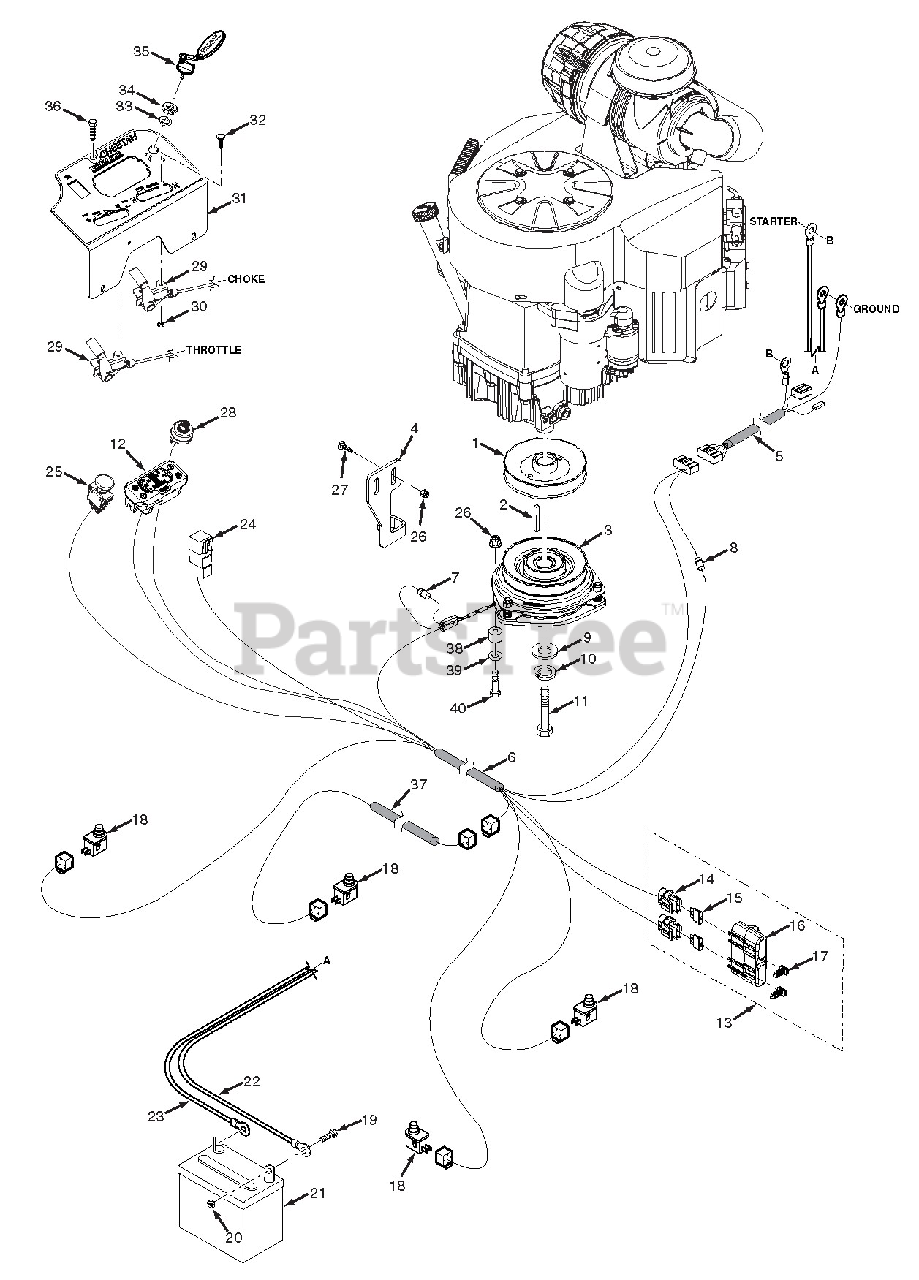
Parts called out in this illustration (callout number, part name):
1	Pulley, 5.80 Dia. - 1.125 Bore
2	Key, 1/4 x 1/4 x 3-1/4"
3	Electric Clutch w/Tag - GT-3.5 (FX850)
3	Electric Clutch w/Tag - GT-5 (FX921)
4	Bracket, Anti-Rotation
5	Wire Harness Adapter, Kawasaki
6	Wire Harness, SCZ
7	Diode, 600V - 6A
8	Diode
9	Flatwasher, 7/16-.469 x 1.75 x .25
10	Lockwasher, 7/16" Spring
11	Bolt, Hex Head 7/16-20 x 2-1/4" w/Patch (Kawasaki)
12	Tiger Eye Cluster Gauge
13	Double Fuse Assembky
14	Fuse Holder
15	Fuse, 20 Amp
16	Cover, Sealed Double
17	Clip, Wire
18	Switch, N.O.
19	Bolt, Hex Head 1/4-20 x 1/2"
20	Nut, 1/4-20
21	Battery
22	Battery Cable, 27" Black
22	Battery Cable, 18" Black (Kohler)
23	Battery Cable, 25" Red
24	Relay
25	Switch, PTO - 10 Amp
26	Nut, FLF HH Elastic Stop 5/16-18
27	Bolt, Carriage 5/16-18 x 1"
28	Keyswitch w/Hardware
29	Control Cable (Kawasaki FX850 Throttle & Choke Cable)
29	Control Cable (Kawasaki FX921 Throttle & Choke Cable)
30	Nut, Elastic Stop #10-24
31	Instrument Panel w/Decal
32	Bolt, Carriage #10-24 x 1/2"
33	Lockwasher, 5/8" Internal
34	Nut, Hex 5/8-32
35	Key, Ignition
35	Key Assembly w/Fob
36	Bolt, Hex Head 1/4-20 x 1/2" Serrated Flange
37	Wire Harness, Operator Platform -SCZ
38	Bushing, UHMW
39	Flatwasher, 5/16-.375 x .875 x .083
40	Bolt, Hex Head 5/16-18 x 1-1/2"
